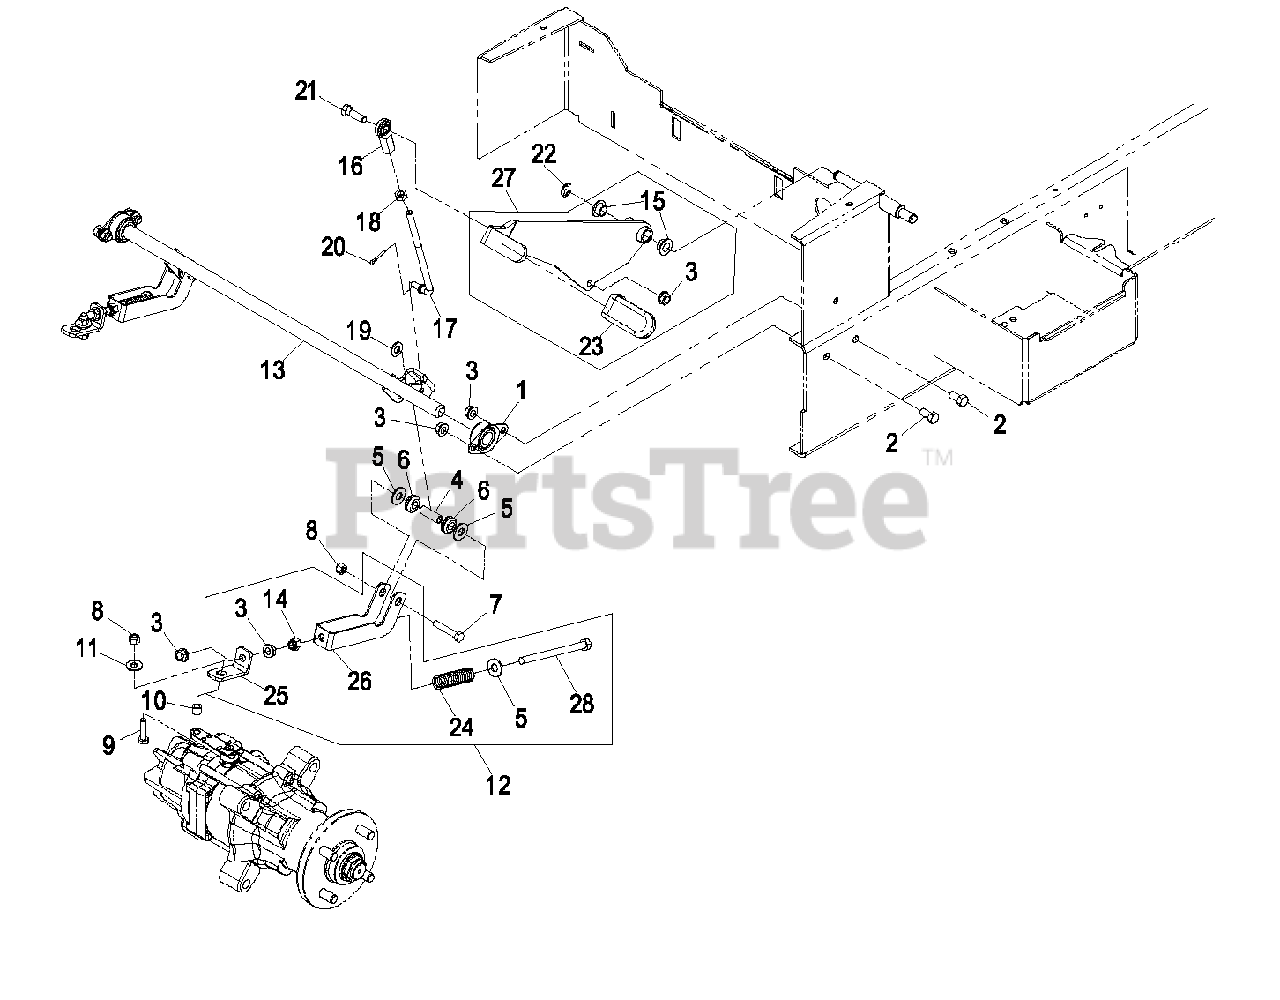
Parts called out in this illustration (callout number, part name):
1	BEARING-FLANGE, SIDE
2	SCREW-HH
3	NUT-HHF, WHIZ
4	SPACER,.438 OD X 1.312 (P
5	WASHER-FLAT
6	GROMMET
7	SCREW-HH
8	NUT-LOCK, NI
9	SCREW-HH
10	BUSHING, LOCATOR
11	WASHER-FLAT
12	ASM,BRAKE LINKAGE
13	WLD,BRAKE CROSS SHAFT
15	BEARING-CONTROL
16	JOINT-BALL, END
17	ROD,LINKAGE BRAKE (PLATED
18	NUT-HEX
19	WASHER-FLAT
20	PIN-COTTER
21	SCREW-HH
22	RING-RETAINING, EXTERNAL
23	GRIP-LEVER
24	SPRING,COMPRESSION
25	LINK,BRAKE (PLATED)
26	CLEVIS,BRAKE (PLATED)
27	ASM,BRAKE LEVER W/GRIP
28	SCREW-HH
